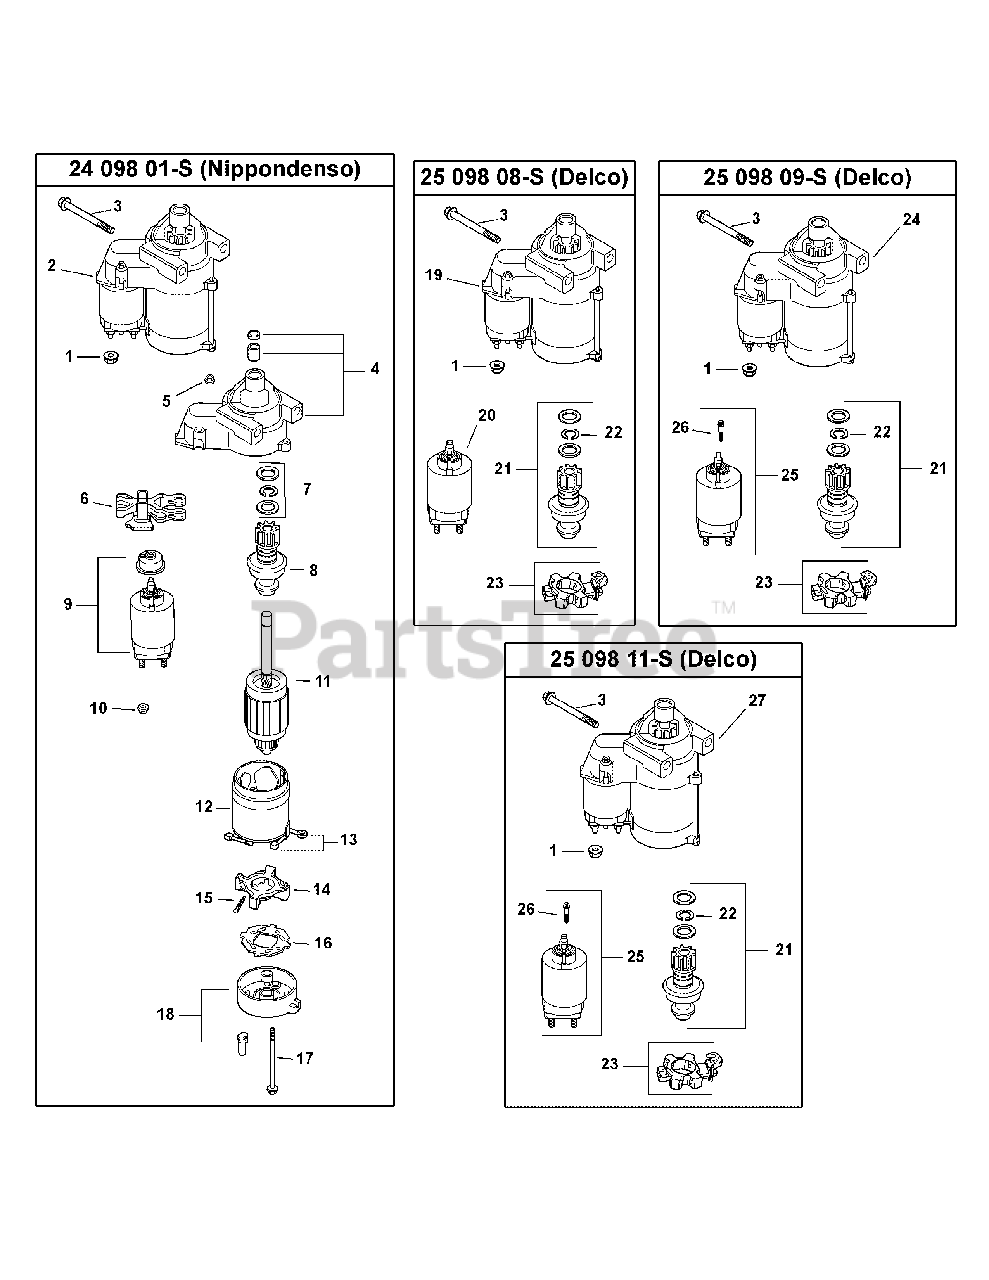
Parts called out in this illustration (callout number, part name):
1	NUT, FLANGE M8X1.25
2	STARTER
4	DRIVE, END CAP
6	LEVER, DRIVE
7	KIT, STARTER REPAIR
8	DRIVE PINION
12	FRAME W/BRUSHES
13	BRUSH HOLDER
14	BRUSH & SPRING KIT
15	SPRING, BRUSH
18	COMMUTATOR, END CAP
19	STARTER, SOLENOID SHIFT
20	SOLENOID
21	KIT, STARTER PINION
22	RING, RETAINING
23	KIT, BRUSH HOLDER
24	STARTER
25	KIT, SOLENOID
26	SCREW, EXTERNAL TORX HEAD
27	STARTER, SOLENOID SHIFT, Delco
